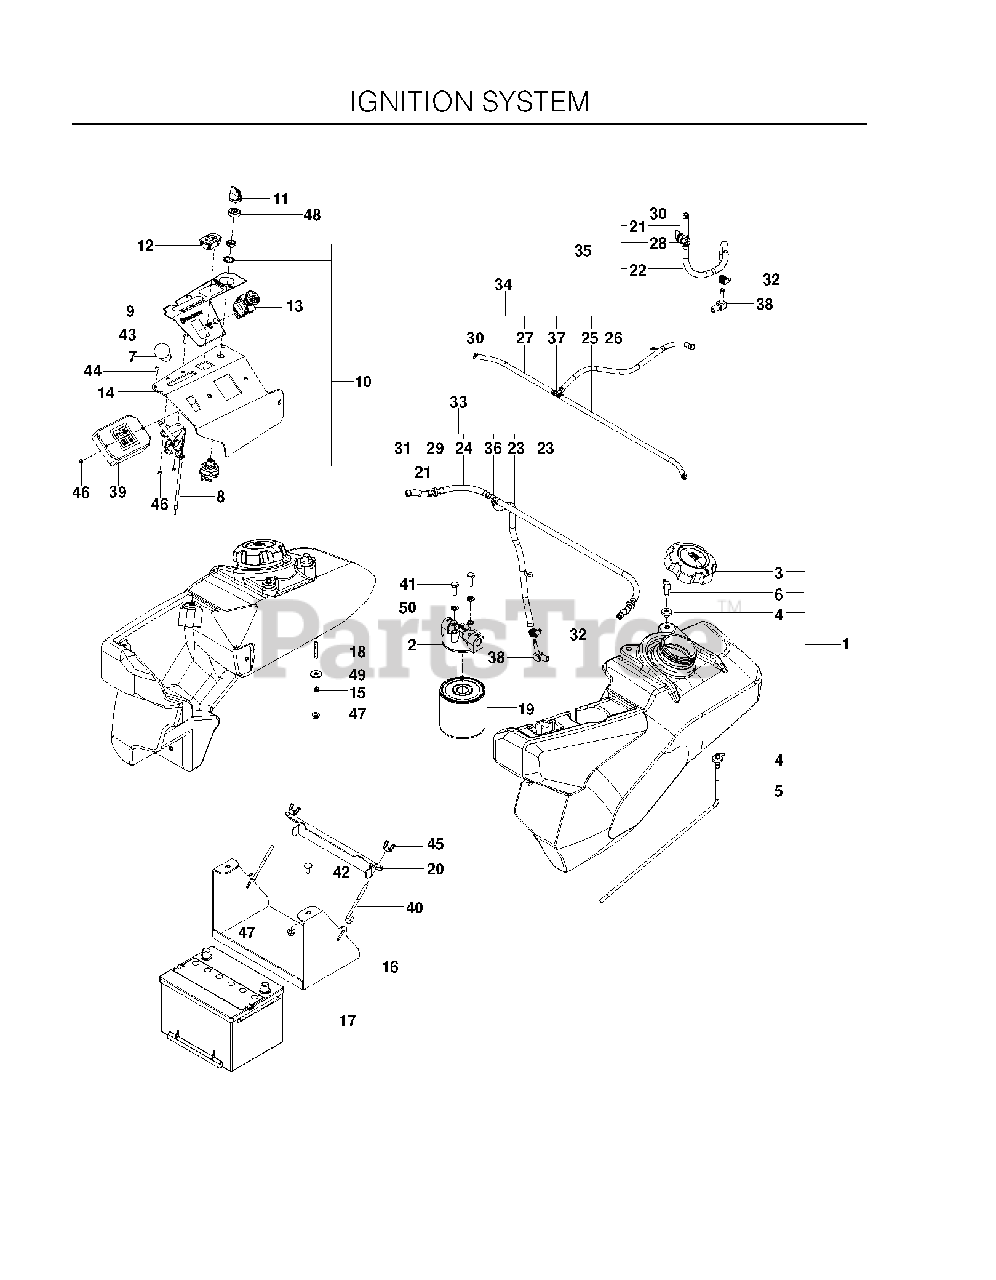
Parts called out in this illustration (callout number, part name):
1	ASSEMBLY, LT TANK, BLK-DIESEL
2	HEAD, FUEL FILTER
4	RUBBER GROMMET
6	FITTING, RETURN, 90
7	KNOB - SHIFT
10	SWITCH, IGNITION, INDAK
11	KEY, IGNITION
12	HOUR METER
13	SWITCH, PTO 10 AMP
16	BOX, BATTERY, BLK
17	BATTERY, 500 CCA
18	STUD, 5/16C
19	FILTER, FUEL
20	BRACKET, BATTERY MOUNT
21	FUEL LINE - 2.5"
22	FUEL LINE 14"
24	FUEL LINE (5")
28	FUEL VALVE
29	VALVE, CHECK, .25
30	HOSE CLAMP
31	CLAMP, HOSE
32	CLAMP, WORM GEAR, NO. 4
35	LINE, FUEL ASSEMBLY
36	TEE, FUEL LINE, .25
38	FITTING, FUEL, 90
39	MODULE, CONTROL
40	HOOK, "J"
41	HCS 1/4C X 3/4 HCS
42	BOLT 5/16C X 3/4" CARRIAGE
43	SCR #10-24 X .75 SKT HD BLK
44	SCR #10-24 X 3/8 SKT HD BLK OX
45	WING NUT 1/4
46	NUT 10-24 NYLOC
47	5/16-18 NYLOC FLANGE NUT
49	FLAT WASHER 5/16 SAE
50	LOCKWASHER 1/4"
